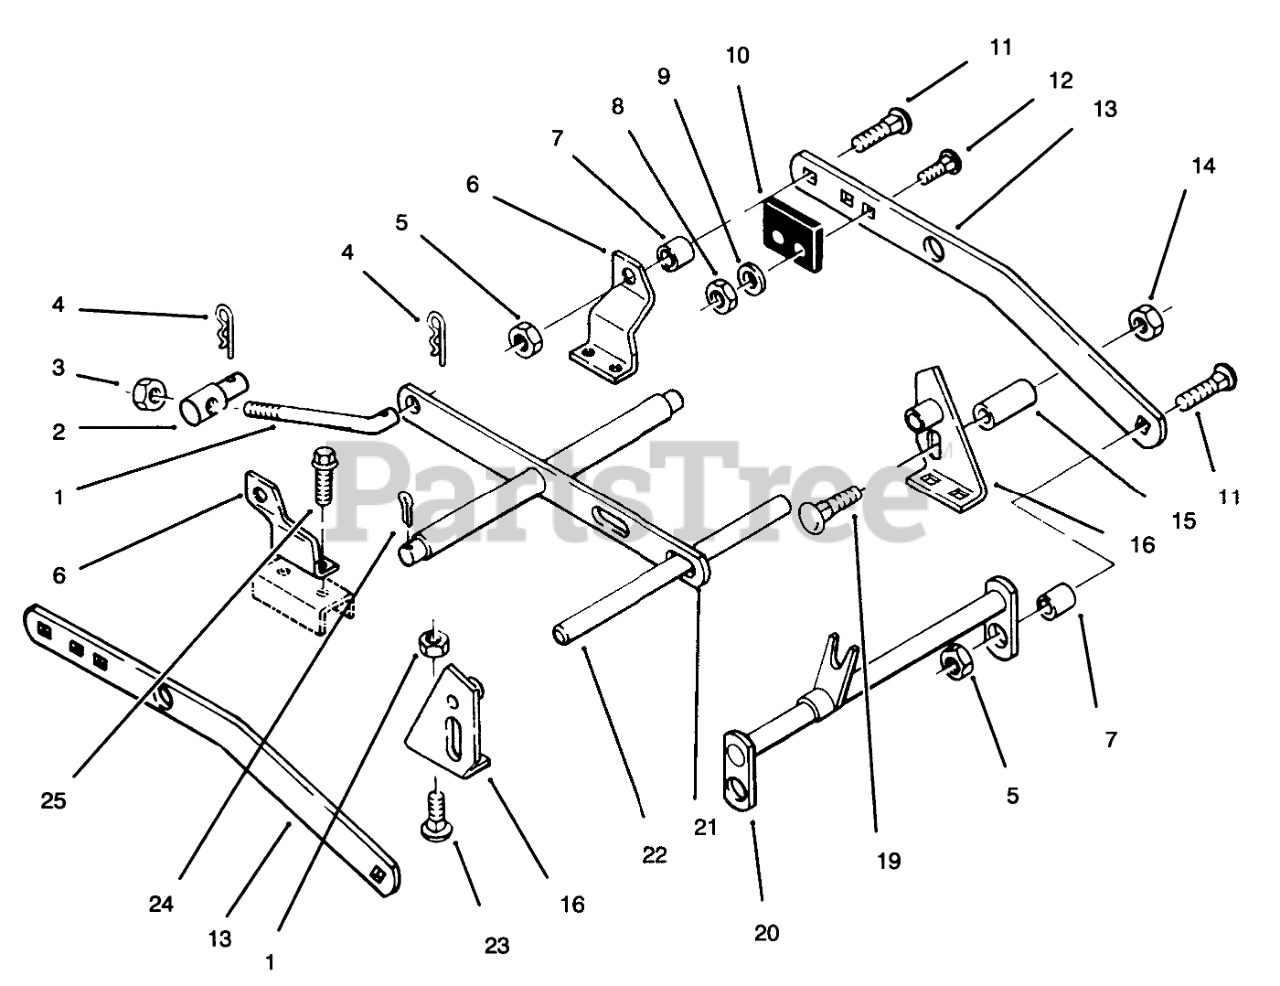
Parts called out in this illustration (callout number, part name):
1	LIFT ROD
2	TRUNNION-LIFT
3	NUT-LOCK, NI
4	PIN-HAIR
5	LOCKNUT-FLANGE
6	Bracket-Rear Deck
7	SPACER
8	NUT-LOCK, NI
9	WASHER-FLAT
10	BUMPER
11	BOLT-CARR
12	SCREW-CARR
13	Bar Draft
14	NUT-LOCK, NI
15	SPACER
16	BRKT-FRNT DCKR
19	BOLT-CARR
20	Hitch
21	Leveler
22	Front Shaft
23	BOLT-CARR
24	PIN-COTTER
25	SCREW-HWH, TAPTITE
